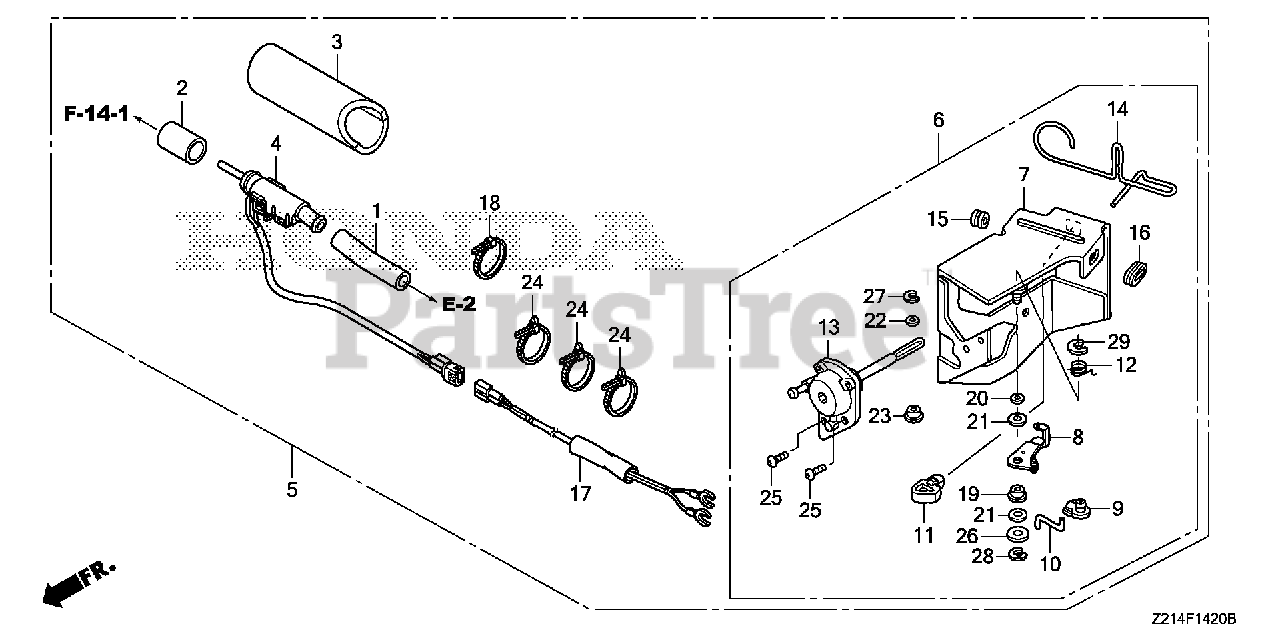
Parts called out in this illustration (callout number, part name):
1	TUBE A, BREATHER
2	TUBE B, BREATHER
3	INSULATOR S, BREATHER TUBE
4	HEATER ASSY., BREATHER (S)
5	HEATER KIT, BREATHER
6	STAY ASSY., MANUAL CHOKE
7	STAY, DIAPHRAGM
8	LEVER, CHOKE
9	JOINT, ROD
10	ROD, CHOKE
11	STOPPER, CHOKE ROD
12	SPRING, MANUAL CHOKE
13	DIAPHRAGM ASSY.
14	ROD, CHOKE CONTROL
15	GROMMET, CHOKE ROD
16	GUIDE, CHOKE ROD
17	SUB-WIRE ASSY.
18	TIE, CABLE (C)
19	BUSH, ARM PIVOT
20	WASHER, CHOKE LEVER
21	SEAL, CHOKE LEVER
22	WASHER, THRUST (2.7X8)
23	COLLAR, LEVER
24	TIE, CABLE (NATURAL 225X5.0)
25	SCREW, PAN (5X12)
26	WASHER, PLAIN (5MM)
27	E-RING (2MM)
28	E-RING (4MM)
29	E-RING (7MM)
